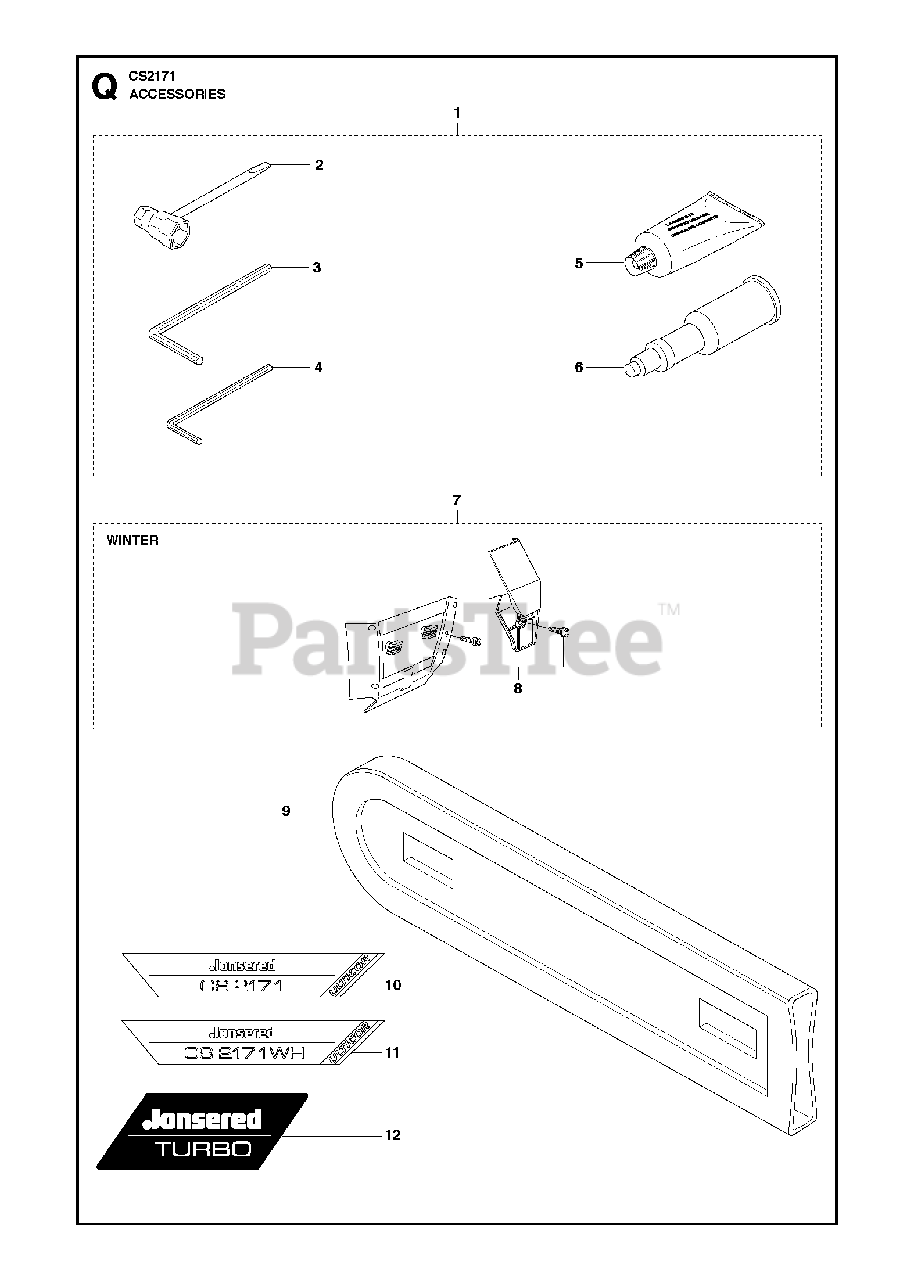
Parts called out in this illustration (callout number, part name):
1	TOOL KIT
2	COMBI TOOL
3	L-SPANNER
4	L-SPANNER
5	GREASE
6	GREASE GUN
7	KIT
8	SCREW
9	BAR COVER
10	LABEL
11	LABEL
